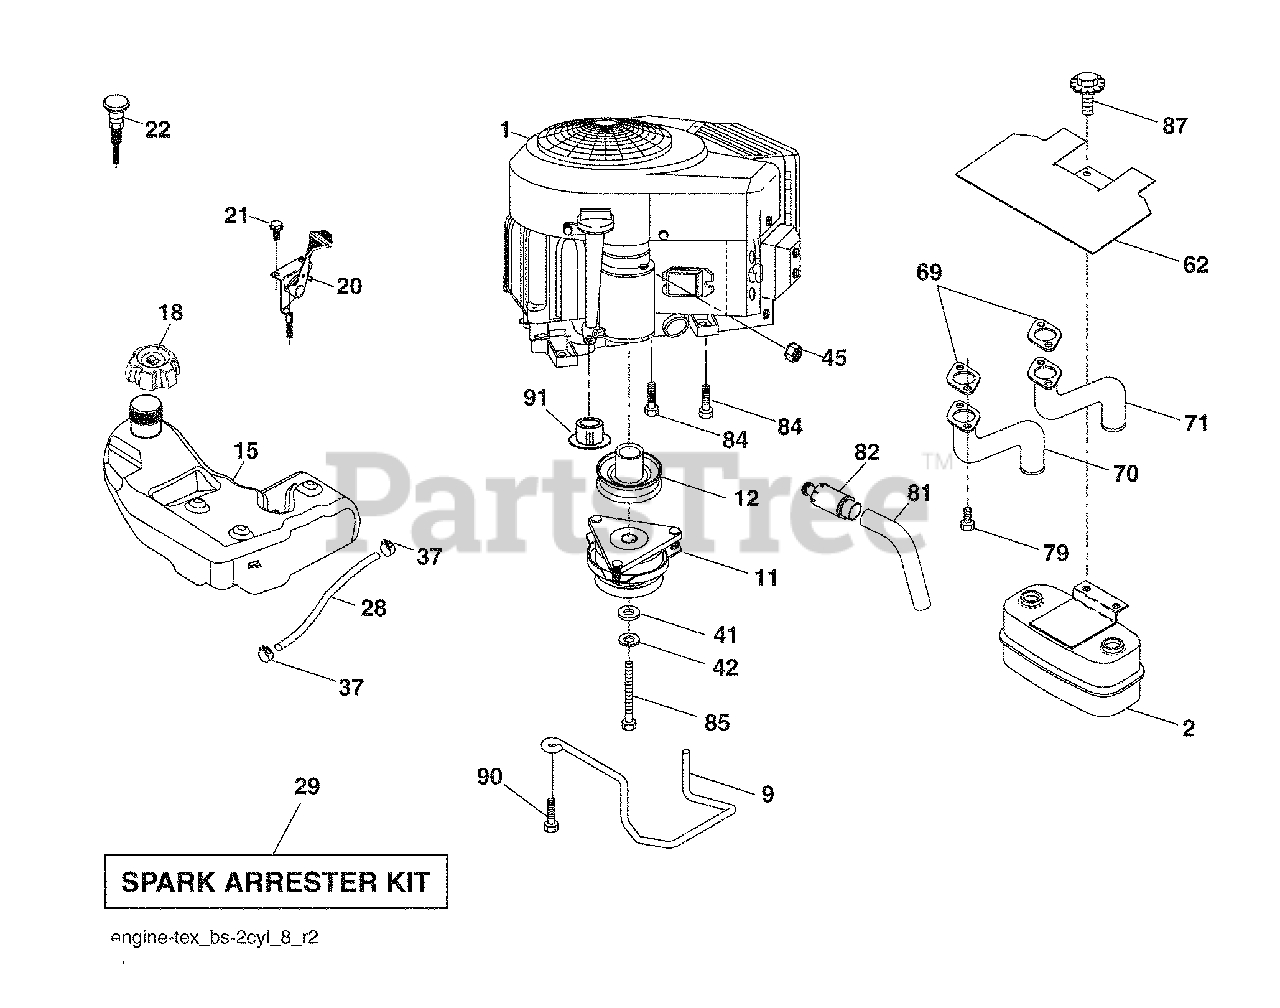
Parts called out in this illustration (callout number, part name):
9	Keeper Belt Engine
11	Clutch Electric
12	Pulley Engine
15	Tank Fuel
18	Cap Asm
20	Control Throttle
21	Screw #10 x 0.750 BOS Thread
22	Control Choke
28	Fuel Line
29	Spark Arrester Kit
37	Clamp Hose
41	Washer 1-1/2 OD x 15/32 ID x .250
42	Washer Lock 7/16
45	Nut Keps Hex 1/4-20 unc
62	Shield Heat Muffler
70	Tube Exhaust LH
71	Tube Exhaust RH
79	Screw Socket Head 5/16-18 x 1
81	Tube Drain Oil Easy
82	Plug Drain Oil
84	Screw 3/8-16 x 1-1/4
85	Bolt Hex 7/16-20 x 4 Gr. 5
87	Bolt 5/16-18 unc x 1 w/Sems
90	Screw 3/8-16 x 1
